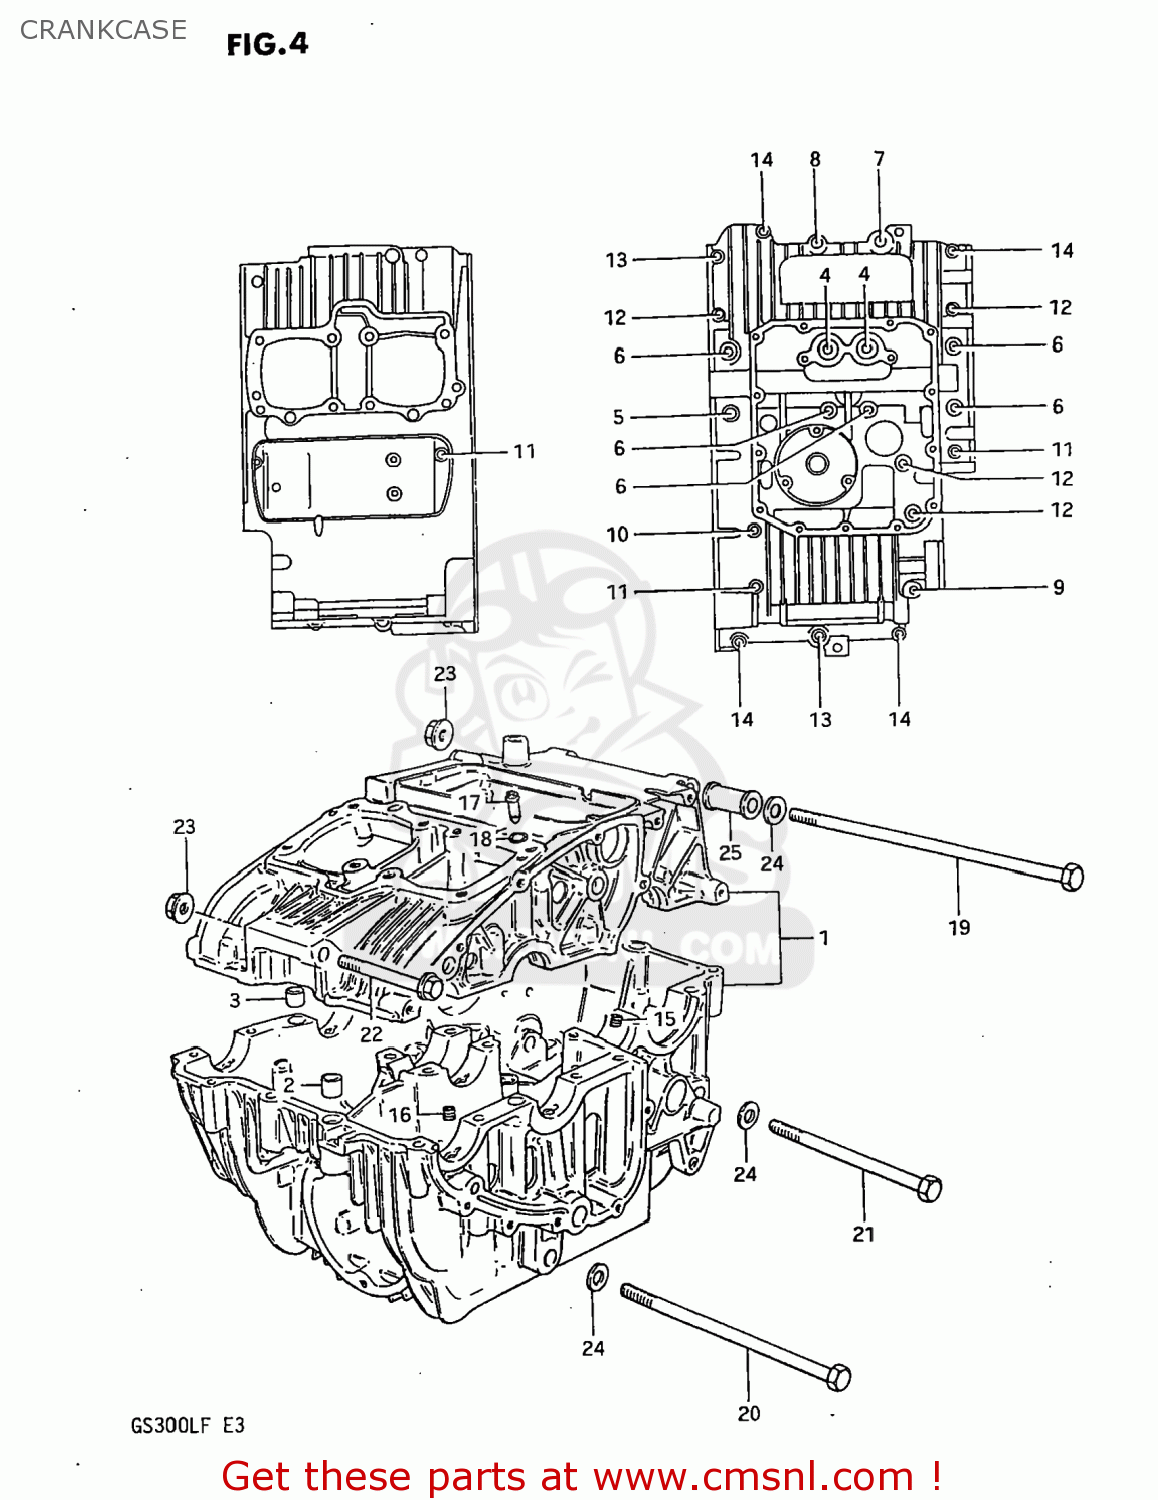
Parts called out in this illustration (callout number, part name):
1	CRANKCASE SET
2	PIN(10.4X13X22)
3	PIN (11X20)(SUS)
4	BOLT (8X70)
5	BOLT
6	BOLT(8X115)
7	BOLT (8X65)
8	BOLT, UPPER
9	BOLT (8X40)
10	BOLT(6X125)
11	BOLT(6X105)
12	BOLT (6X90)
13	BOLT ,6X60
14	BOLT (6X45)
15	JET,AIR(100)
16	JET,AIR
17	JET,AIR
18	O RING(D:1.05,ID:3.1)
19	BOLT
20	BOLT
21	BOLT
22	BOLT (10X90)
23	NUT 10MM
24	WASHER
25	SPACER,ENGINE MOUNT
